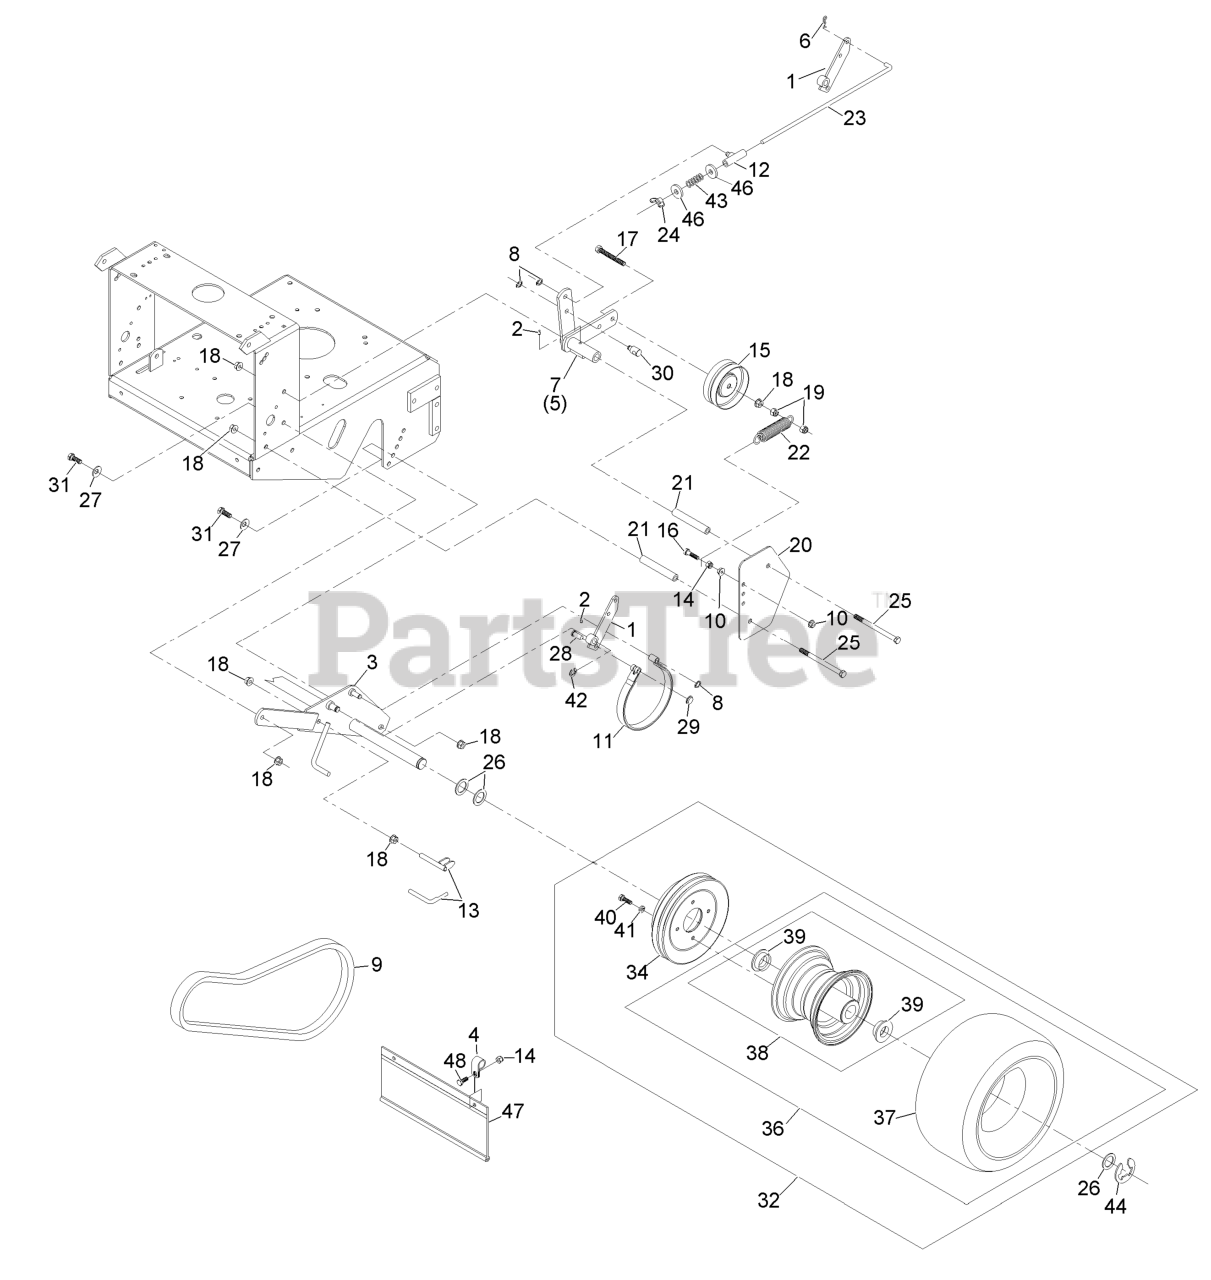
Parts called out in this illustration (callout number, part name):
1	ARM-BRAKE
2	FITTING-GREASE
4	CLAMP-R
6	PIN-COTTER
8	RING-RETAINING
9	BELT,WHEEL DRIVE
11	BAND-BRAKE
12	SWIVEL-BRAKE
13	SCRAPER
14	NUT-LOCK, NI
15	IDLER-WHEEL, DRIVE
16	SCREW-HH
17	SCREW-HH
18	NUT-HHF, WHIZ
19	NUT-LOCK, NI
20	SHIELD-WHEEL, DRIVE
21	SPACER-SHIELD
22	SPRING-EXTENSION
23	LINKAGE-BRAKE
24	WINGNUT-NYLOCK
25	SCREW-HH
26	WASHER-SPACER
27	WASHER-BELLEVILLE
28	PIN-CLEVIS
29	RING-RETAIN,PUSH,EXT,FLAT
30	SWIVEL-LEVER, DRIVE
31	SCREW-HH
32	DRIVE WHEEL ASM
34	DRUM AND SHEAVE ASM
36	WHEEL AND TIRE ASM
37	TIRE-TURFMASTER
38	WHEEL AND HUB ASM
39	BEARING-FLANGED
40	SCREW-HH
41	WASHER-LOCK
42	RING-RETAINING, EXTERNAL
43	SPRING-COMPRESSION
44	RING-SNAP
46	WASHER-PLAIN
47	SHIELD-TRAILING
48	SCREW-HH
